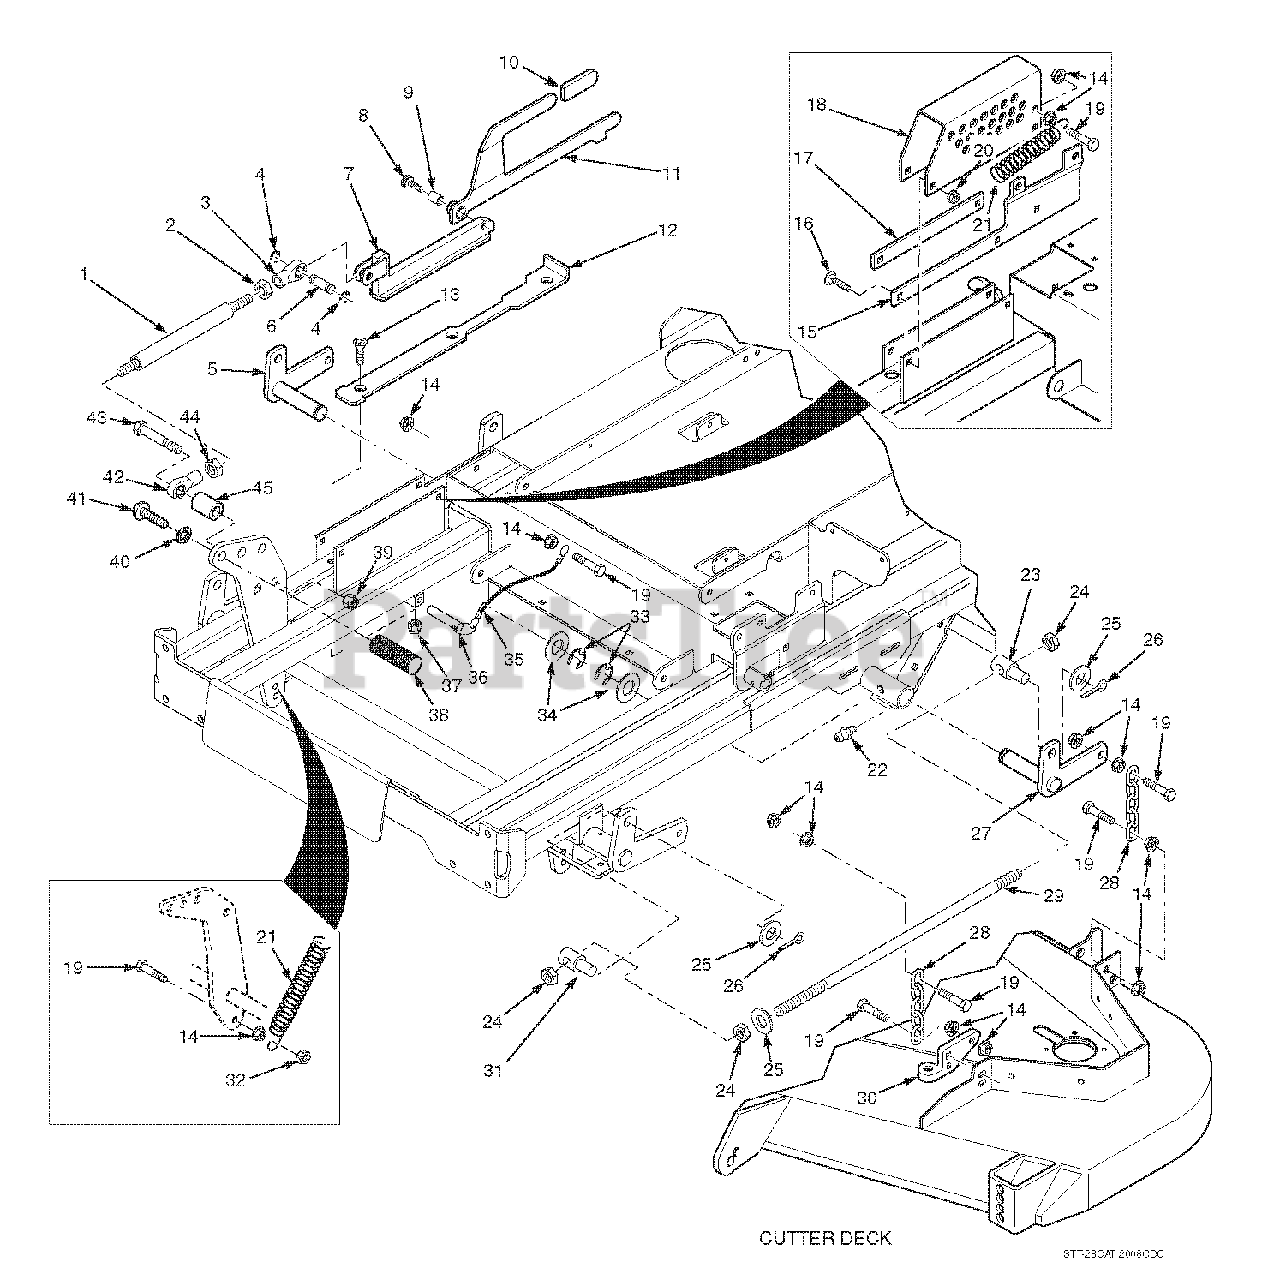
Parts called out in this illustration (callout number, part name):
1	Link, Deck Lift
2	Nut, Jam 1/2-20 LH
3	Rod End, Female - 1/2-20 LH
4	Ring, Retaining 1/2" External "E"
5	Bellcrank Weldment, RH Rear
6	Pin, Decklift
7	Slide Weldment, Height Adjustment
8	Bolt, Shoulder 1/2 x 3/4"
9	Bushing, .502 ID.
10	Grip, Deck Latch
11	Deck Latch
12	Lockplate, Decklift
13	Screw, Cap 5/16-18 x 3" FHHS
14	Nut, Hex Serrated Flange 3/8-16
15	Guide, Long
16	Bolt, Carriage 5/16-18 x 1"
17	Guide, Short
18	Bracket, Cutting Height Adjustment
19	Bolt, Hex Head 3/8-16 x 1-1/2"
20	Nut, Hex Serrated Flange 5/16-18
21	Spring, Helper
22	Grease Fitting
23	Swivel Joint, LH
24	Nut, Hex 5/8-11
25	Flatwasher, 5/8" (.656 x 1.312 x .095)
26	Cotter Pin, 3/16 x 1"
27	Bellcrank Weldment, LH Rear
28	Chain
29	Stud, 5/8-11 x 26.0"
30	Lever Assembly, Deck Level
31	Swivel Joint, RH
32	Locknut, 3/8-16 Center Lock
33	Ring, Retaining 1" External "E"
34	Flatwasher, 1" (1.062 x 1.50 x .048)
35	Lanyard, Deck Height Pin
36	Ring Pin, 1/2 x 3.06"
37	Nut, 3/8-16 Elastic Stop
38	Foot Pedal, Height Adjustment
39	Nut, Hex Elastic Stop 1/2-13
40	Lockwasher, 5/8"
41	Capscrew, 5/8-11 x 1-1/2"
42	Rod End, Female - 1/2-20 RH
43	Bolt, Hex Head 1/2-13 x 3"
44	Nut, Jam 1/2-20 RH
45	Spacer, Decklift Pedal
